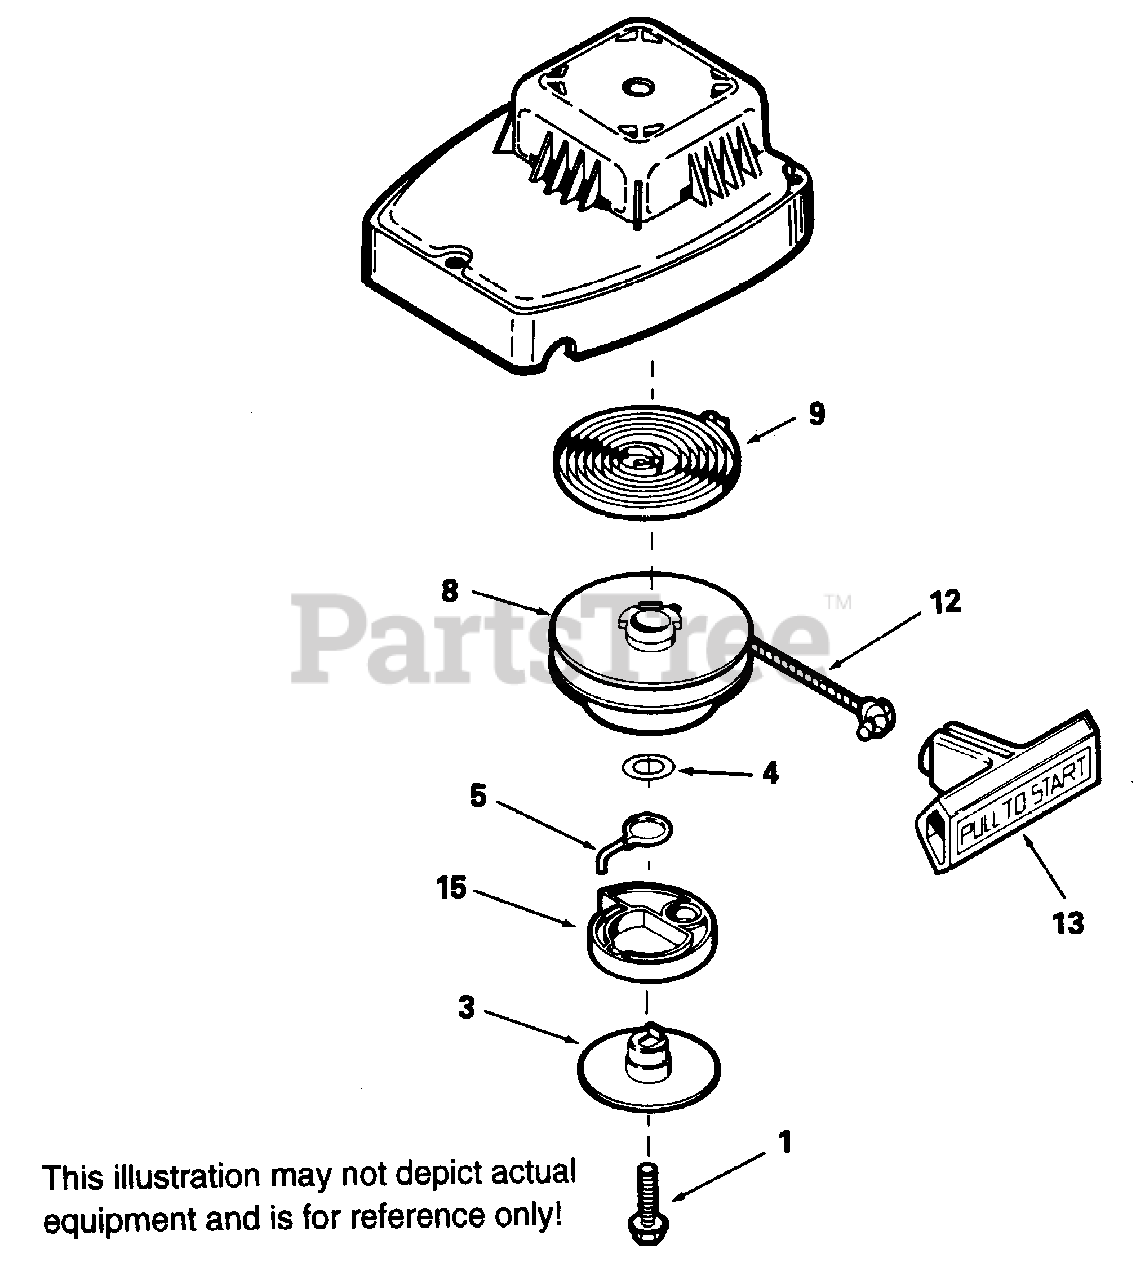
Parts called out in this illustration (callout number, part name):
1	Screw, Retainer
3	Retainer, Pawl
5	Spring, Brake
8	Pulley, Starter
9	Spring, Rewind
12	Rope, Starter ( #4 rope, 71" long)
13	Handle, Starter
